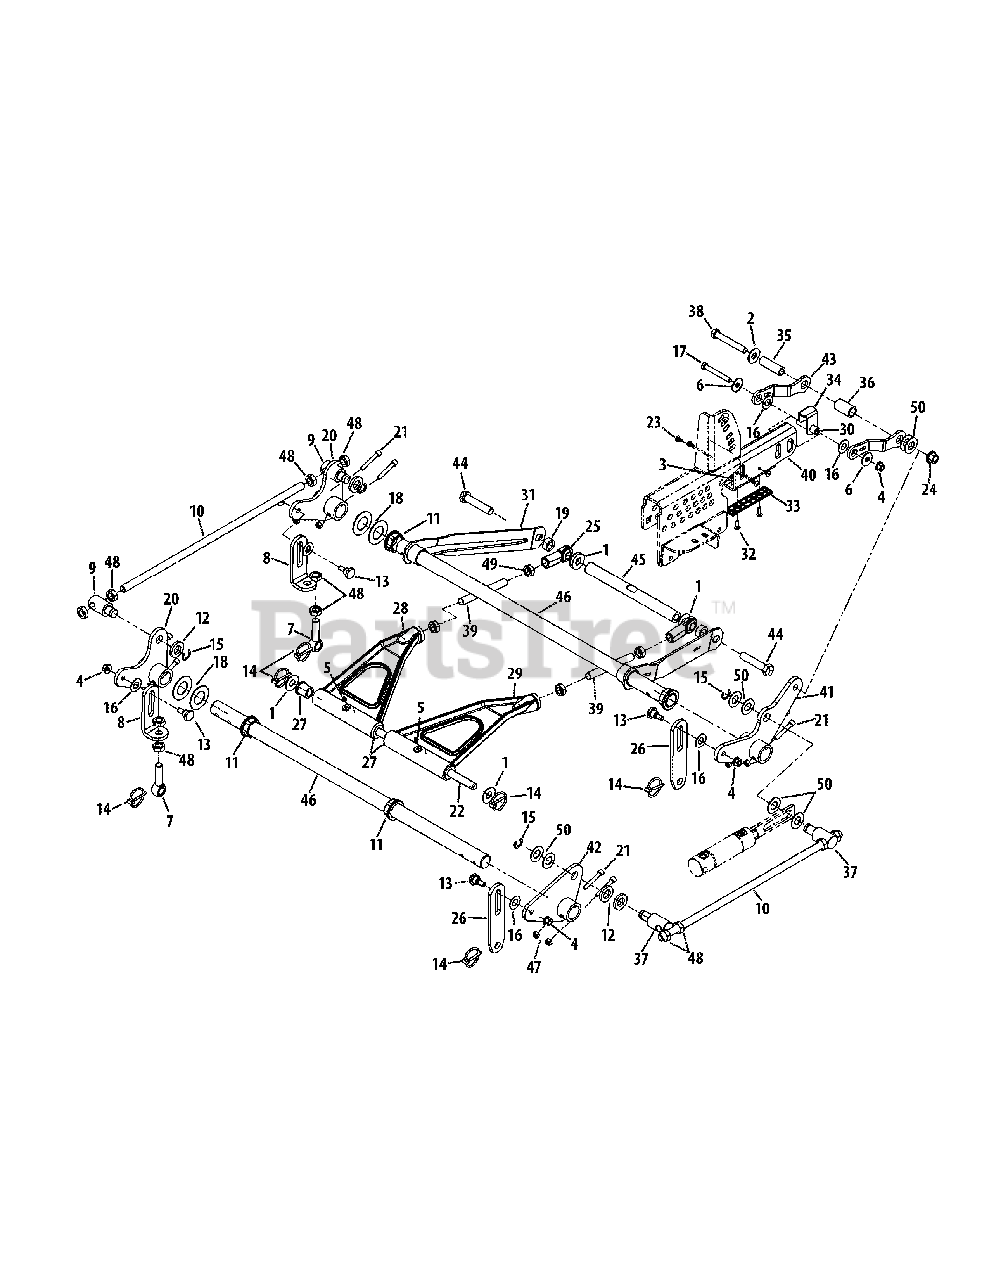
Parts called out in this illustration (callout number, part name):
1	Washer, .655 x 1.5 x .055
2	Washer, .563 x 1.38 x .109
3	Nut, 1/4-20
4	Flg. Cnter. Lock Nut, 3/8-16 (60" Deck)
4	Flange Lock Nut, 3/8-16 (72" Deck)
5	Grease Fitting, 1/4-28
6	Washer, .411 x 1.25 x 1.00
7	Eye Bolt, 5/8-16 x 2.63
8	Eye Bolt Link, 5/8
9	Lift Ferrule
10	Lift Connecting Rod
11	Hex Flange Bearing
12	Spacer, .812 x 1.47 x .218
13	Shoulder Bolt, 3/8-16 x .625 x .437
14	Lynch Pin, 3/16 x 1.25
15	Retainer Clip
16	Washer
17	Hex Screw, 3/8-16 x 3.00
18	Washer, 1.25 x 2.25 x .075
19	Spacer, .630 x 1.06 x .440
20	Assembly Bellcrank
21	Screw, 5/16-18 x 2.0
22	Deck Lift Link Rod (60" Deck)
22	Deck Lift Link Rod (72" Deck)
23	Rivet, 1/4 x .625
24	Flange Top Lock Nut, 1/2-13
25	RH Rod End, 5/8
26	Deck Lift Link
27	Flange Bearing
28	LH Lift Brace Bearing
29	RH Lift Brace Bearing
30	Spacer, .375 x .625 x 2.20
31	Front Frame Support Assembly
32	Flat Head Screw, 1/4-20 x .750
33	Wear Plate, 1.125 x 5.0
35	Spacer, .510 x .750 x 2.38
36	Spacer, .765 x 1.00 x 1.70
37	Lift Ferrule, 1.938
38	Hex Screw, 1/2-13 x 3.5
39	Rod, 5/8-18 x 5.5 (60" Deck)
39	Rod, 5/8-18 x 3.5 (72" Deck)
40	Tube, 3.0 x 1.5
41	Hydro Assist Bellcrank
42	Lift Bellcrank Assembly
43	Loft Offset Yoke Bracket
44	Hex Screw, 5/8-11 x 3.00
45	Front Lift Link Mount Shaft
46	Deck Lift Shaft
47	Hex Lock Nut, 5/16 -18
48	Jam Nut, 5/8-11
49	Jam Nut, 5/8-18
50	Flat Washer, .76 x 1.49 x .06
